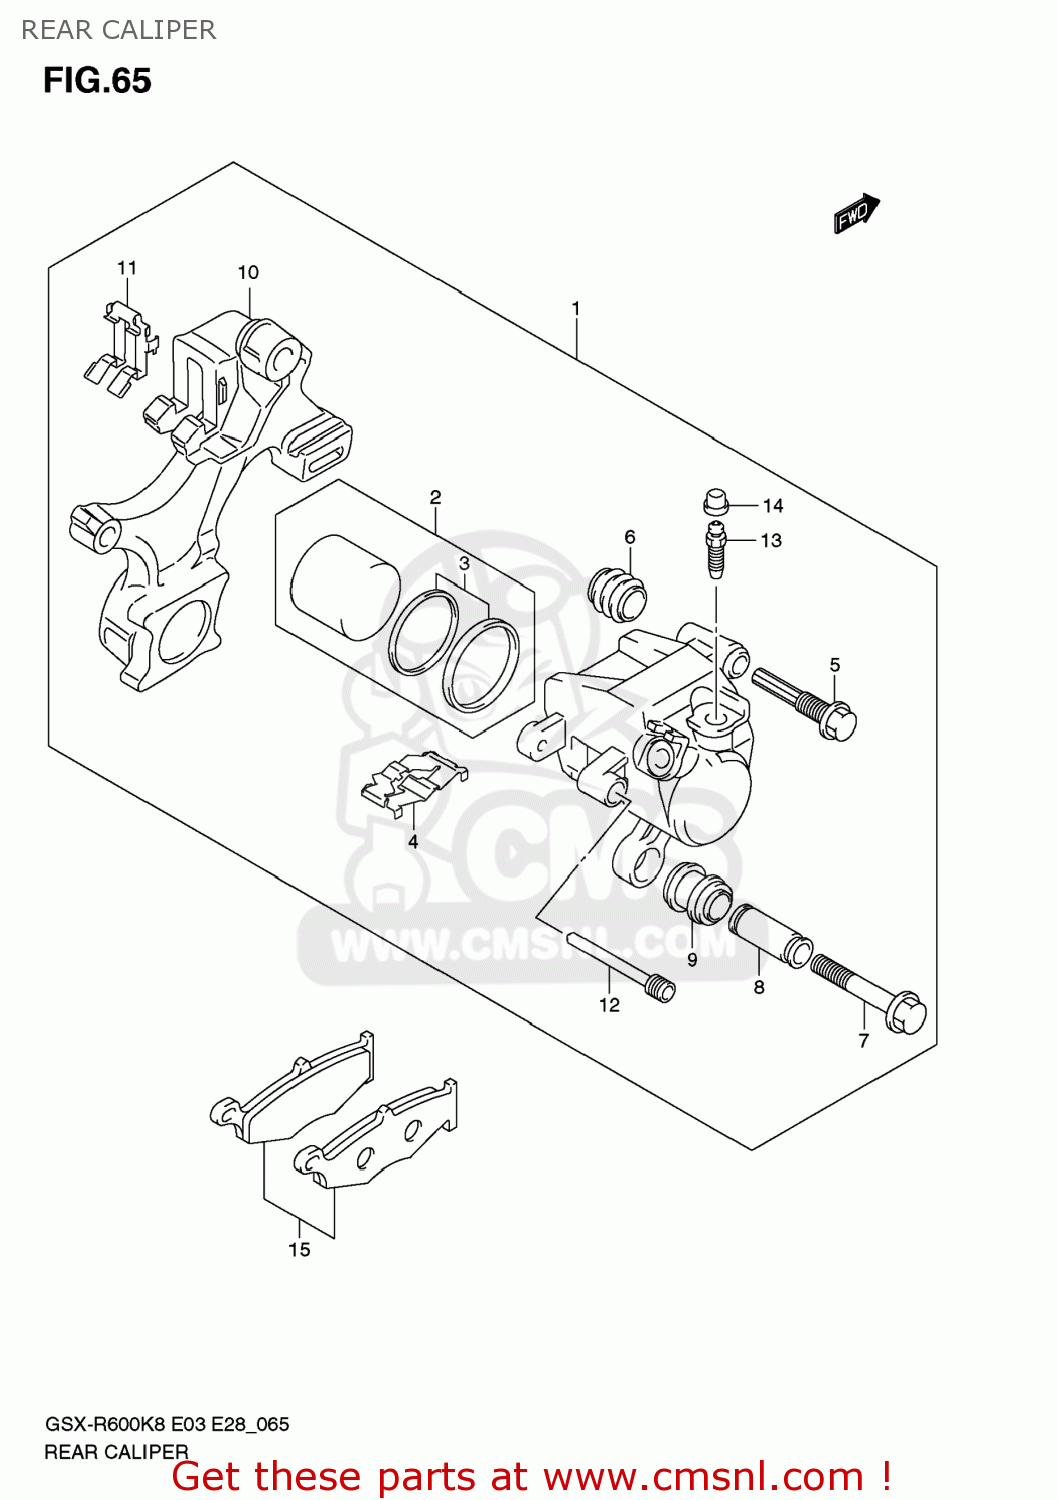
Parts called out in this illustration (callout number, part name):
1	CALIPER ASSY,RR
2	PISTON SET
3	SEAL SET,PISTON
4	SPRING,PAD
5	PIN,BOLT
6	BOOT,AXLE
7	BOLT
8	SLEEVE
9	BOOT,SLEEVE
10	BRACKET
11	RETAINER
12	PIN,PAD
13	BLEEDER
14	CAP,BLEEDER PLUG
15	PAD SET (NAS)
